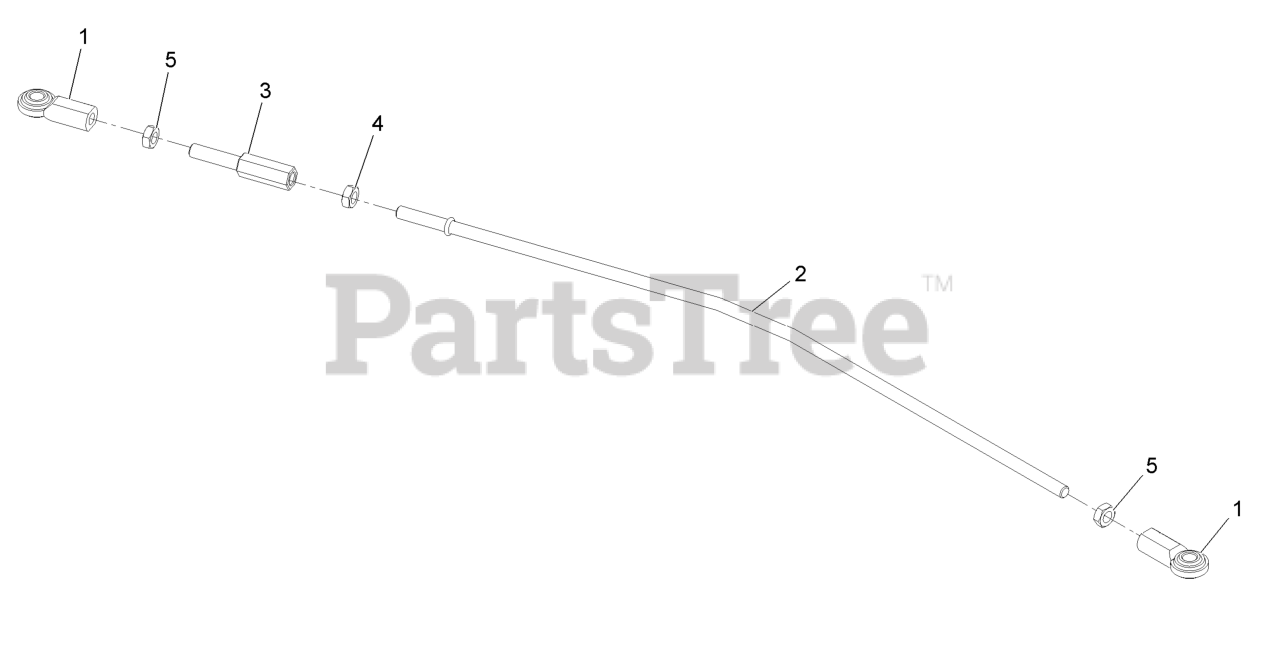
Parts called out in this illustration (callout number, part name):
1	JOINT-BALL, END
2	LINK-LOWER, MOTION CONTRO
3	ROD-ADJUSTMENT
4	NUT-HEX JAM, LH
5	NUT-HJ
